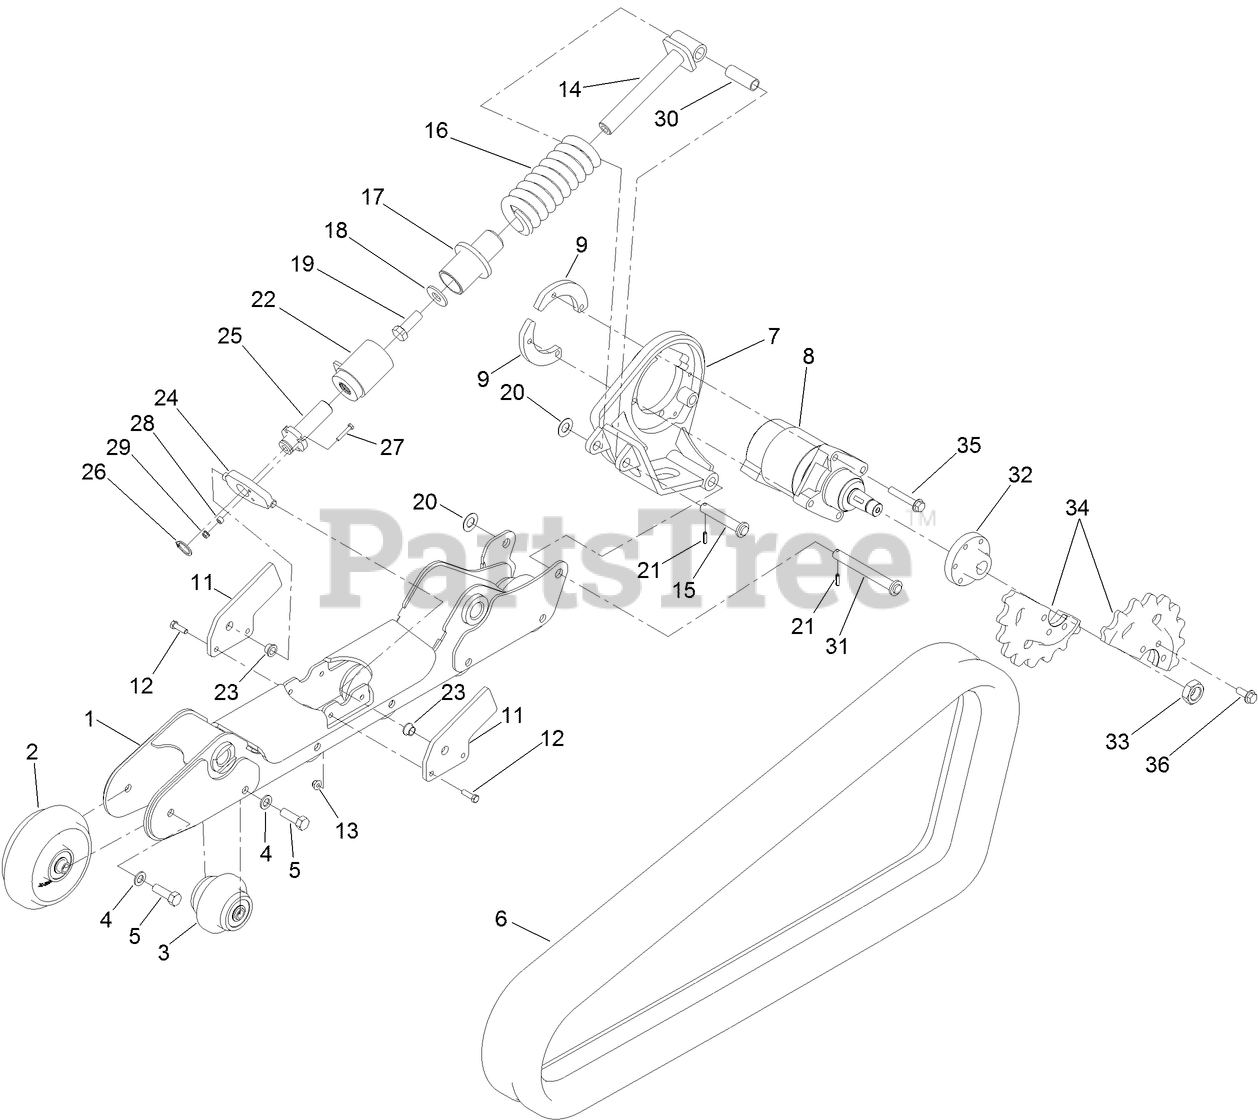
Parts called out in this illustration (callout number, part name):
1	FRAME-TRACK, LH
2	WHEEL-ASM TENSIONER
3	WHEEL-ASM CAMSO
4	WASHER-FLAT
5	SCREW-HH
6	TRACK-NARROW
7	MOUNT-MOTOR, LH
8	MOTOR-HYD
9	PLATE-MOUNTING, WHEELMOTOR
11	PLATE-EAR, INSIDE
12	SCREW-HH
13	NUT-HF, NI
14	TENSIONER-SPRING
15	PIN-TENSIONER
16	SPRING-COMPRESSION
17	GUIDE-TENSIONER
18	WASHER
20	WASHER-FLAT
21	PIN-SPRING
22	HOUSING-TENSIONER
23	BUSHING-BELLCRANK
24	PLATE-PIVOT
25	SCREW-TENSIONER
26	RING-RETAINING, EXTERNAL
27	SCREW-HH
28	SPACER
29	NUT-HHF
30	SPACER-PIVOT
31	PIN-PIVOT
32	HUB-SPROCKET,
33	NUT-HEX
34	SPROCKET-18 TOOTH
35	SCREW-HF
36	SCREW-HHF
